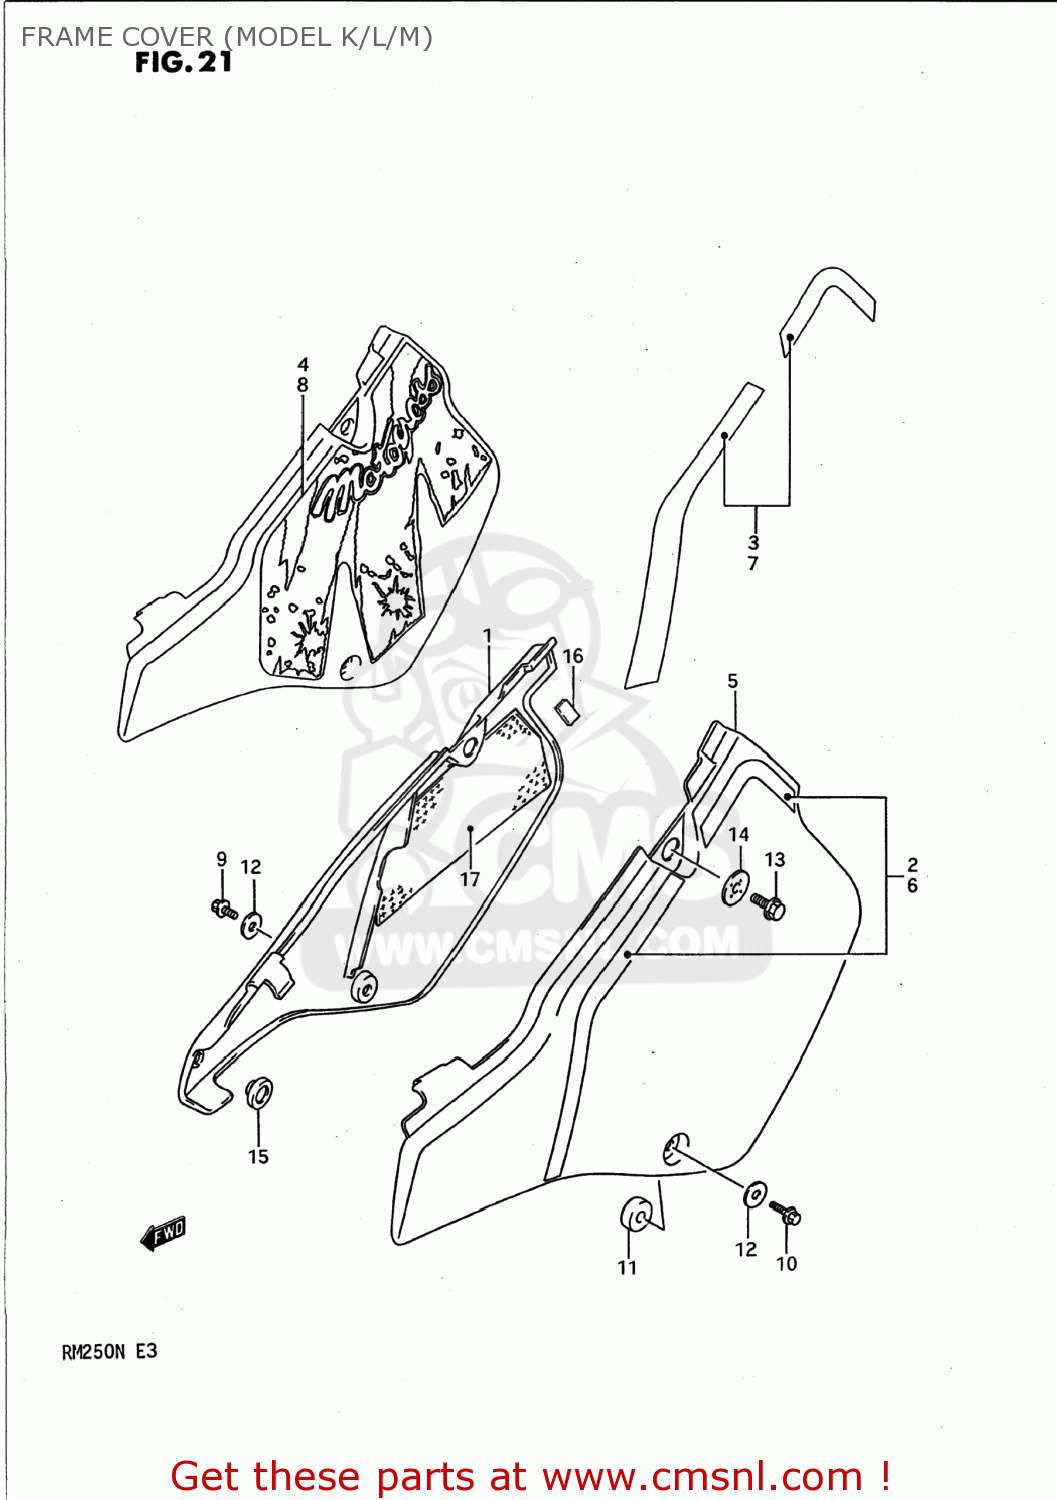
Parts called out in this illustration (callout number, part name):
1	COVER,FRAME,RIGHT
2	EMBLEM,FRAME COVER,RIGHT (BLUE)
3	TAPE SET,FRM COVER NO.PL,R
4	EMBLEM,FRAME COVER,RIGHT
5	COVER,FRAME,L(WHITE)
6	EMBLEM,FRAME COVER
7	TAPE SET,FRAME COVER,LEFT (B
8	TAPE SET,FRAME COVER NO
9	BOLT
10	BOLT
11	SPACER(6.5X20X9)
12	GASKET(6.5X20X1.5) (NAS)
13	BOLT
14	WASHER
15	CUSHION
16	CUSHION,FRAME COVER,REAR
17	SHIELD,FRAME COVER,RIGHT
